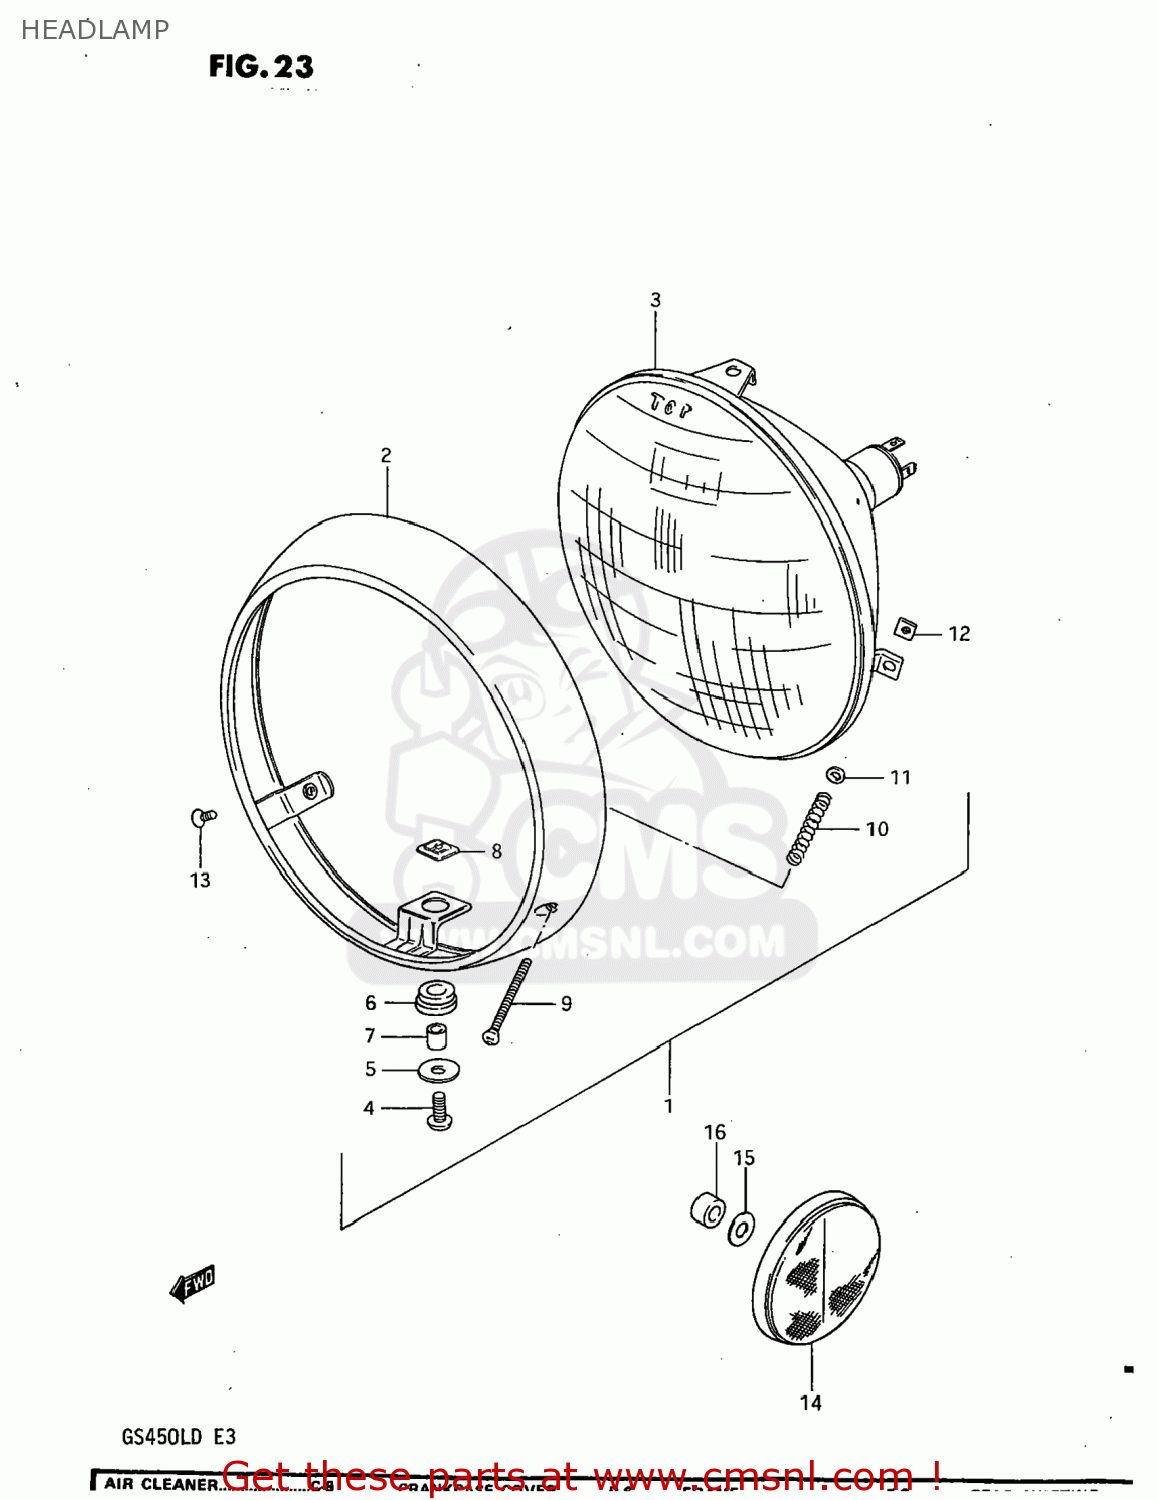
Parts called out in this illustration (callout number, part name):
1	LAMP ASSEMBLY,HEAD
2	RIM
3	LAMP UNIT
4	SCREW
5	WASHER
6	CUSHION
7	SPACER
8	NUT
9	SCREW
10	SPRING
11	WASHER
12	NUT,HEADLAMP ADJUSTER
13	SCREW(5X12)
14	REFLECTOR,REFLEX
15	WASHER
16	SPACER (5.5X9.5X6.5)
